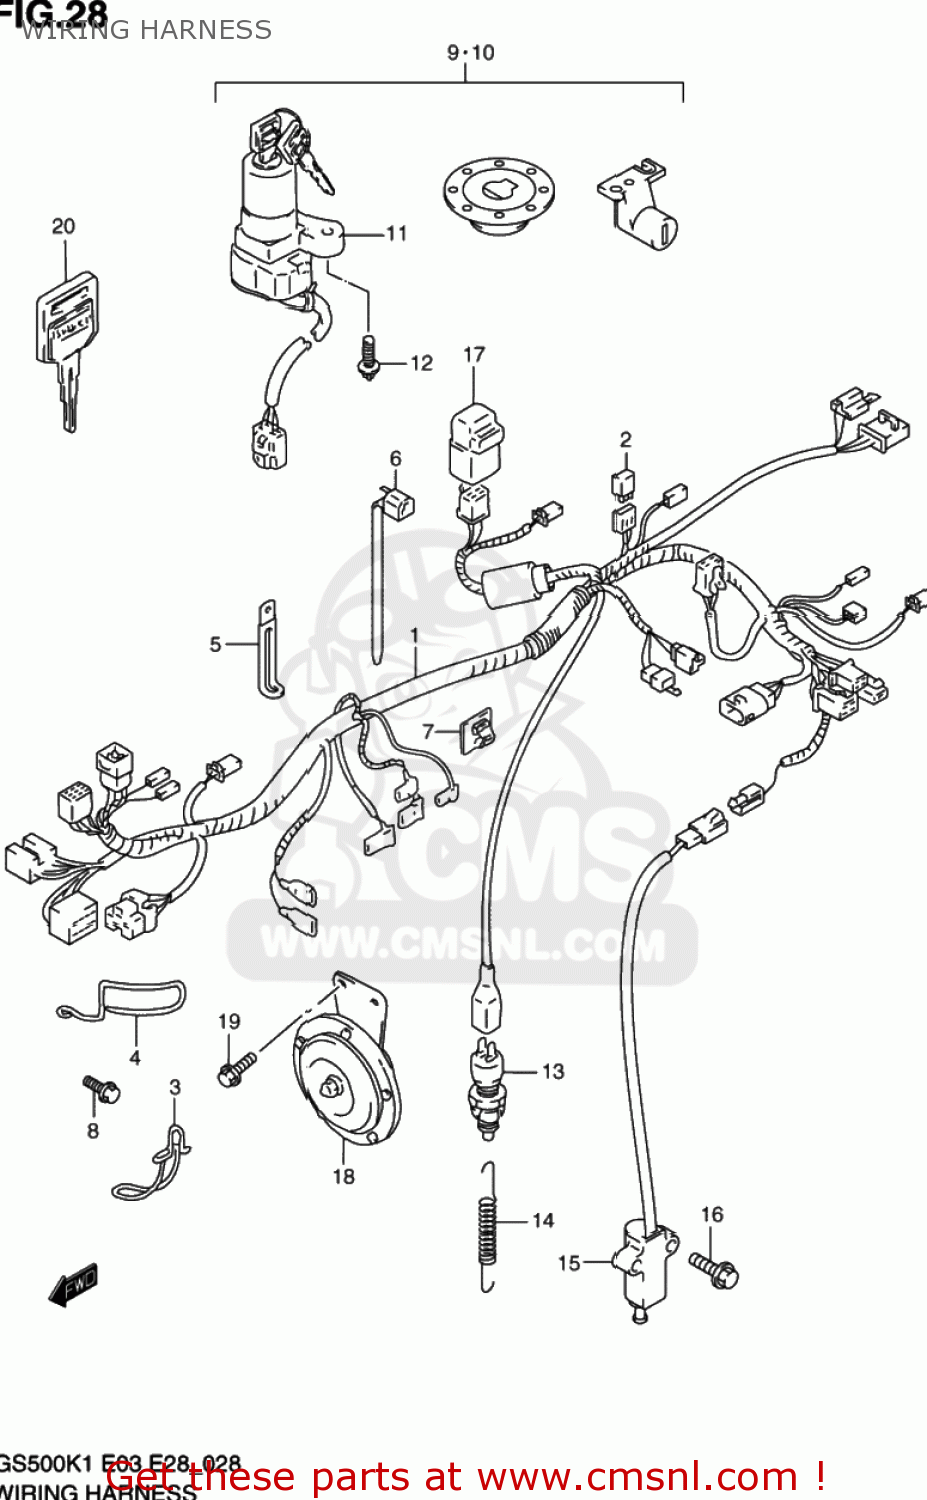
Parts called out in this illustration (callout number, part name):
1	HARNESS,WIRING
2	DIODE(STANLEY DE8804)
3	PROTECTOR
4	PROTECTOR
5	CLAMP(L:65)
6	CLAMP(L:125)
7	CLAMP
8	BOLT
9	LOCK SET
10	LOCK SET
11	LOCK ASSY,STEERING
12	SCREW(6X18)
13	SWITCH ASSY,STOP LAMP
14	SPRING
15	SWITCH ASSY,SIDE STAND WARNING
16	BOLT
17	RELAY ASSY
18	HORN ASSY
19	BOLT
20	KEY,BLANK
